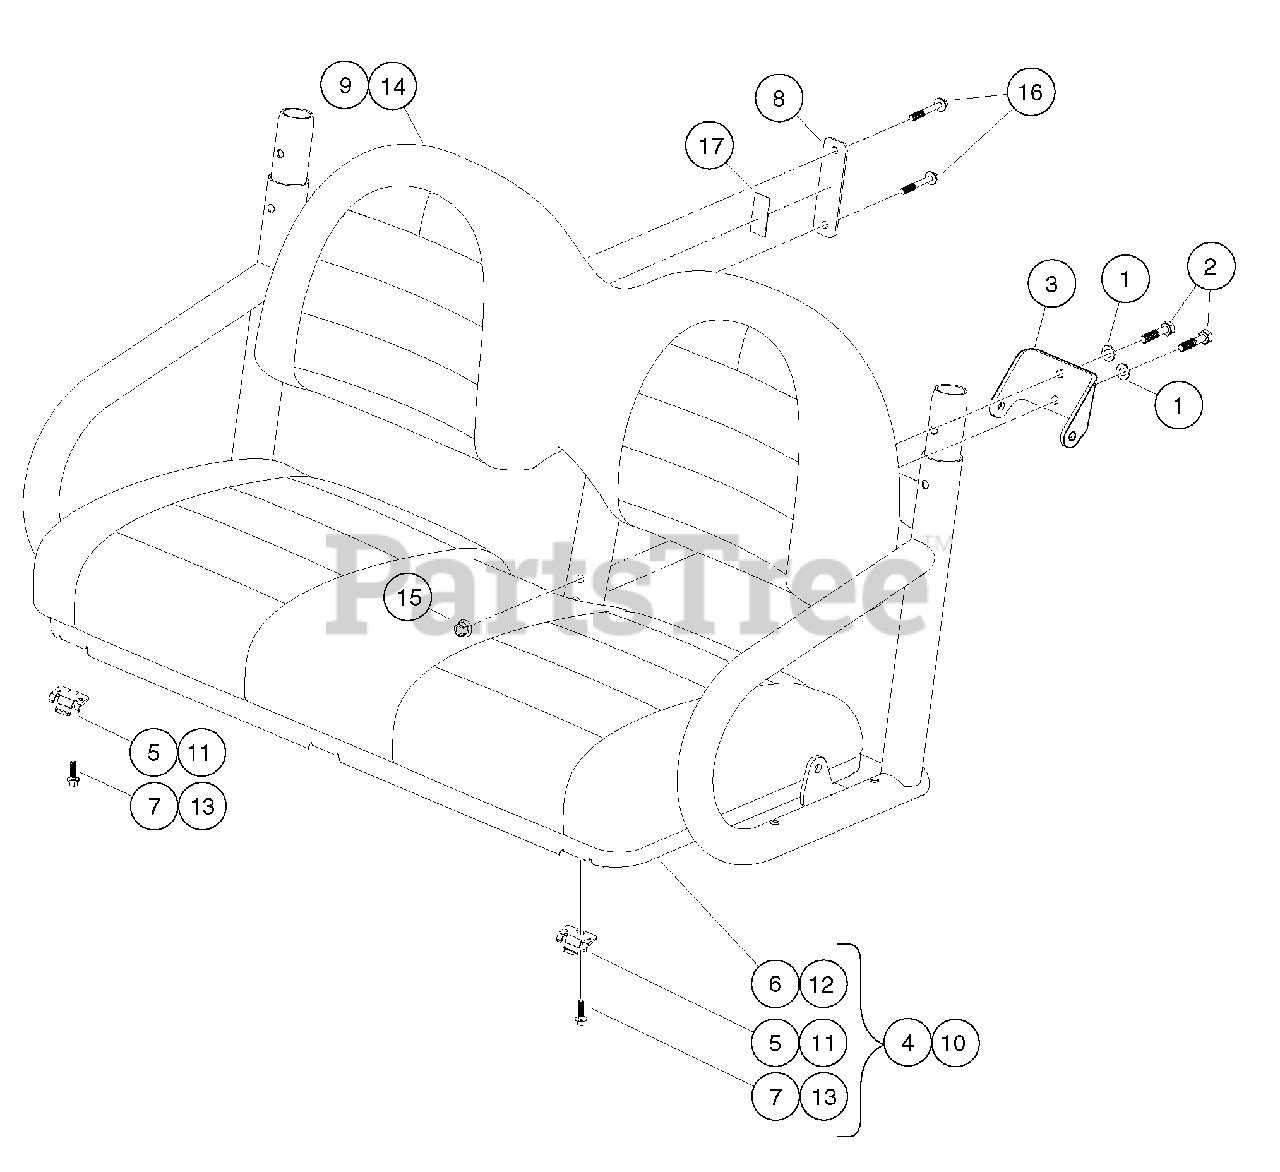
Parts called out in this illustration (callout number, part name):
1	Washer, Hard, M10, Zn-Ni/Blk
2	Bolt, M10 X 45, Zn-Ni (Black)
3	Bracket, Seat Belt, Bench
4	Asm, Seat Bottom, Bench, Gray
5	Hinge Plate
6	Asm, Seat Bottom, Bench
7	Bolt Flg Blk, M8 X 25, Loctite
8	Bracket, Seat Back, AWD
9	Seat Back, Bench, Gray
10	Asm, Seat Bottom, Bench, Black
11	Hinge Plate
12	Seat Bottom, Bench, Black
13	Bolt Flg Blk, M8 X 25, Loctite
14	Seat Back, Bench, Black
15	Nut, Flanged, M10 x 1.5, Black
16	Bolt Flg Blk, M8 X 55, Loctite
17	Tape, Double-Sided, VHB, 1"x 2"
